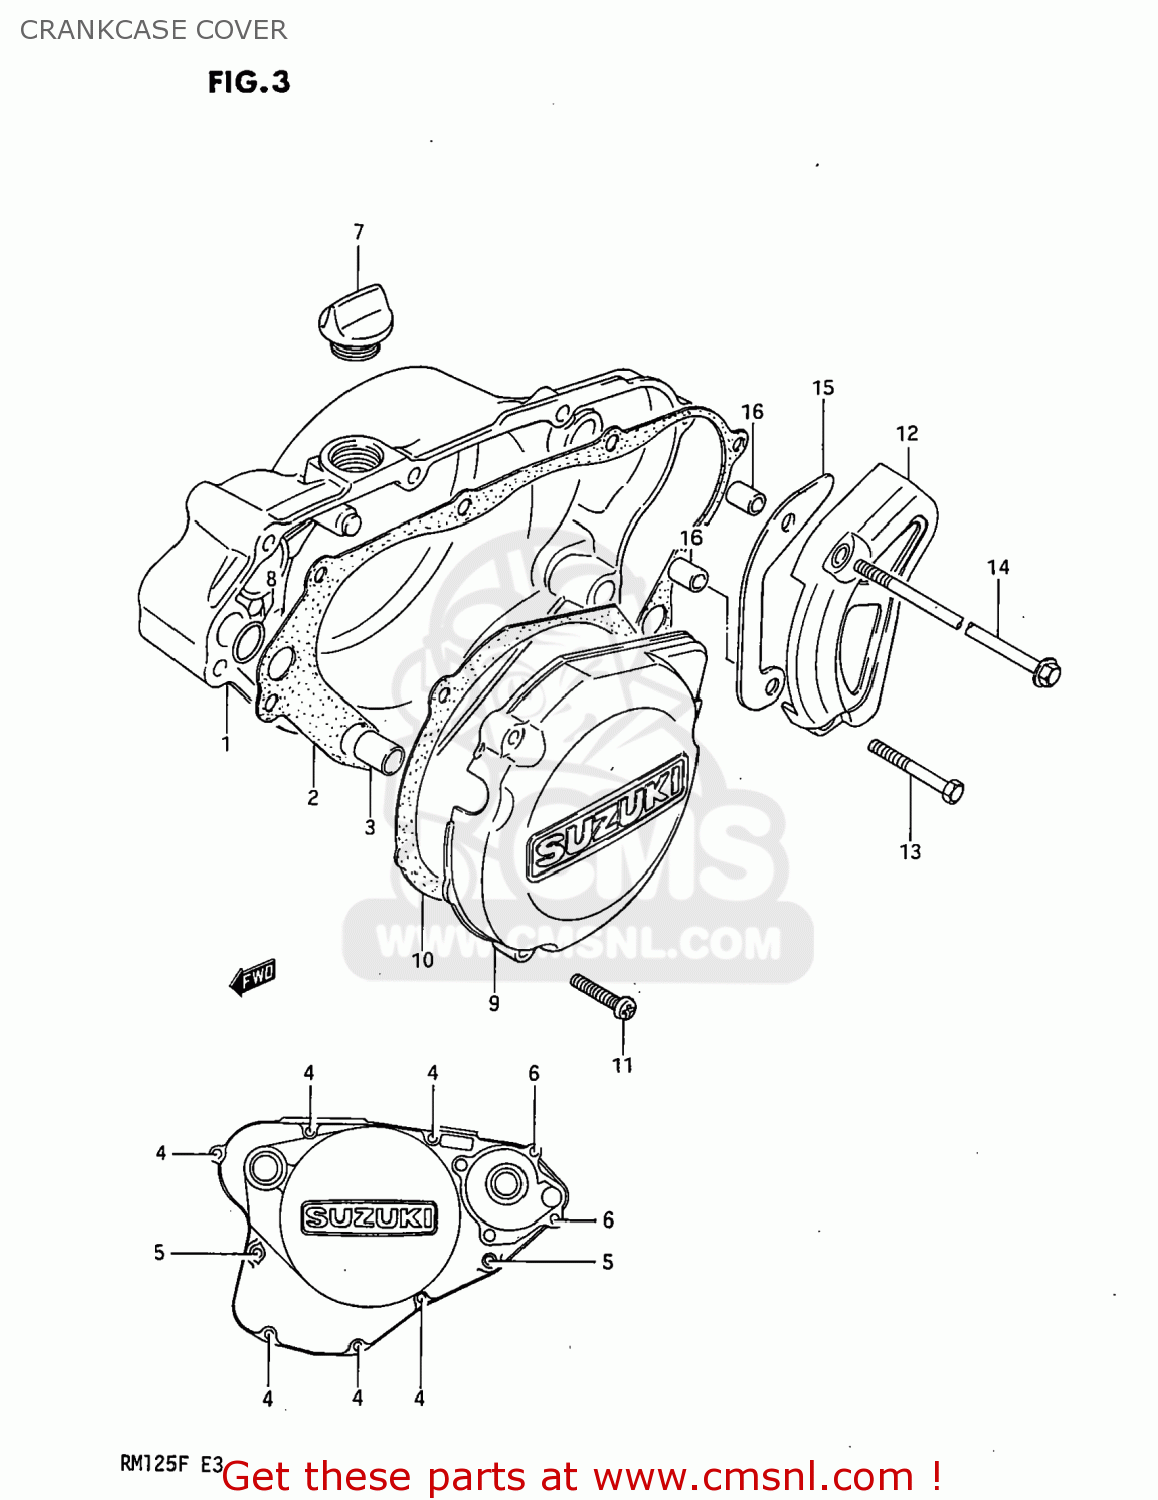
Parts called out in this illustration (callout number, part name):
1	COVER,CLUTCH
2	GASKET,CLUTCH COVER (MCA)
3	PIN
4	SCREW
5	SCREW
6	SCREW
7	PLUG SET
8	O RING(D:1.9,ID:14.5)
9	COVER,MAGNETO
10	GASKET,MAGNETO COVER (MCA)
11	SCREW
12	COVER,SPROCKET
13	BOLT
14	BOLT(6X105)
15	PLATE,CHAIN GUIDE
16	SPACER(6.5X10.5X12)
